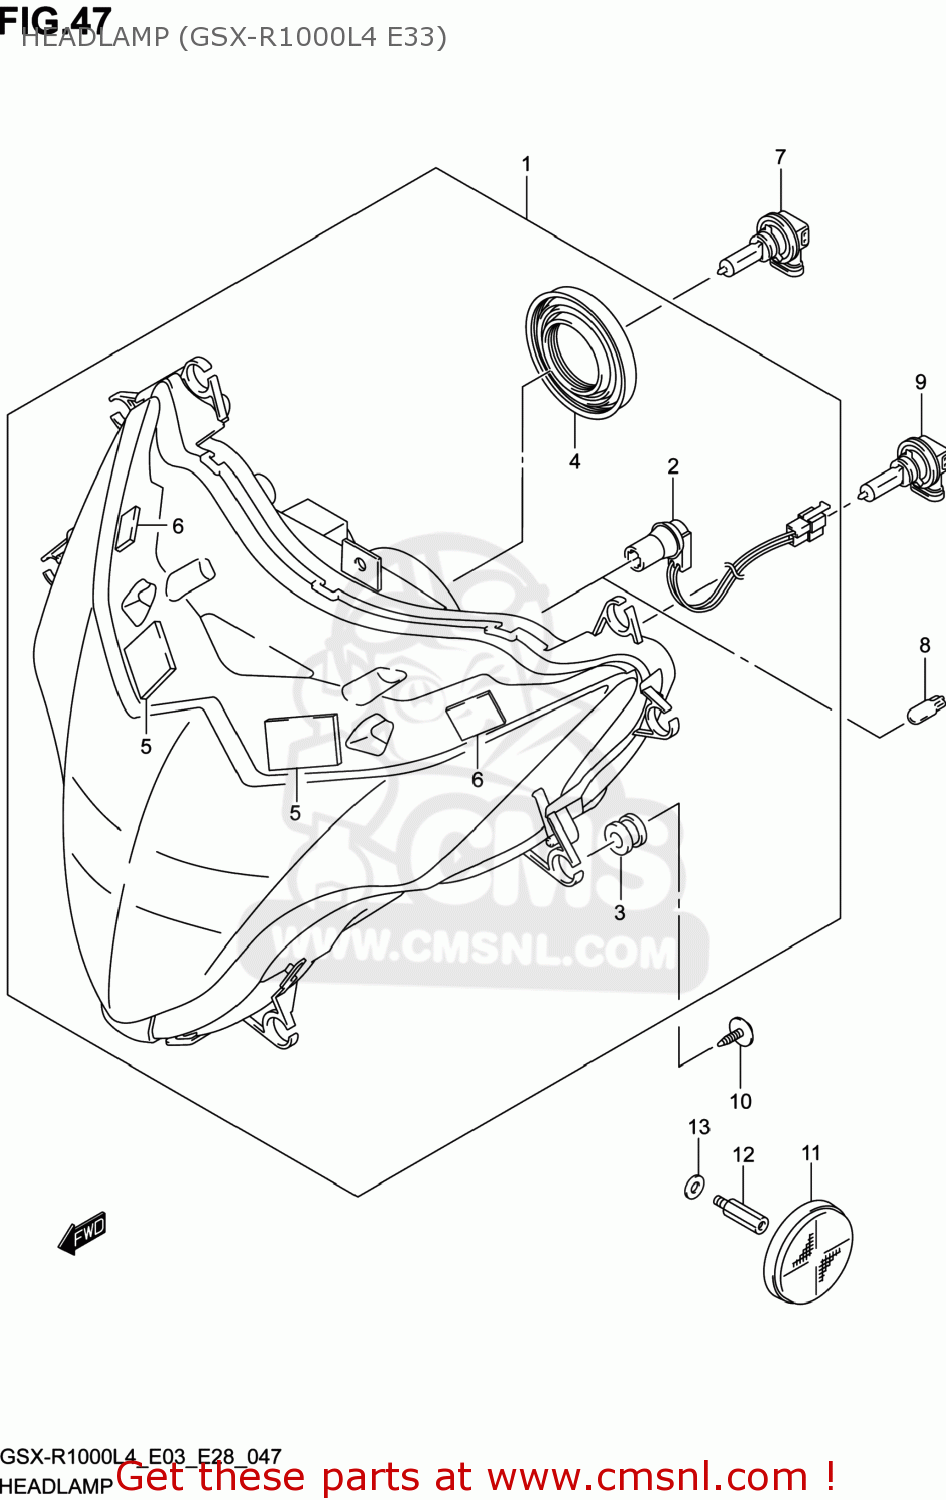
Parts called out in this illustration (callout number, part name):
1	HEADLAMP ASSY
2	CORD ASSY
3	CUSHION
4	COVER,SOCKET
5	FASTENER
6	FASTENER,COWLING
7	BULB(12V55W,H11)
8	BULB(12V5W)
9	BULB(12V65W,H9)
10	SCREW(5X15)
11	REFLEX REFLECTOR ASSY,FR SIDE
12	BOLT
13	WASHER(8.5X18X1)
